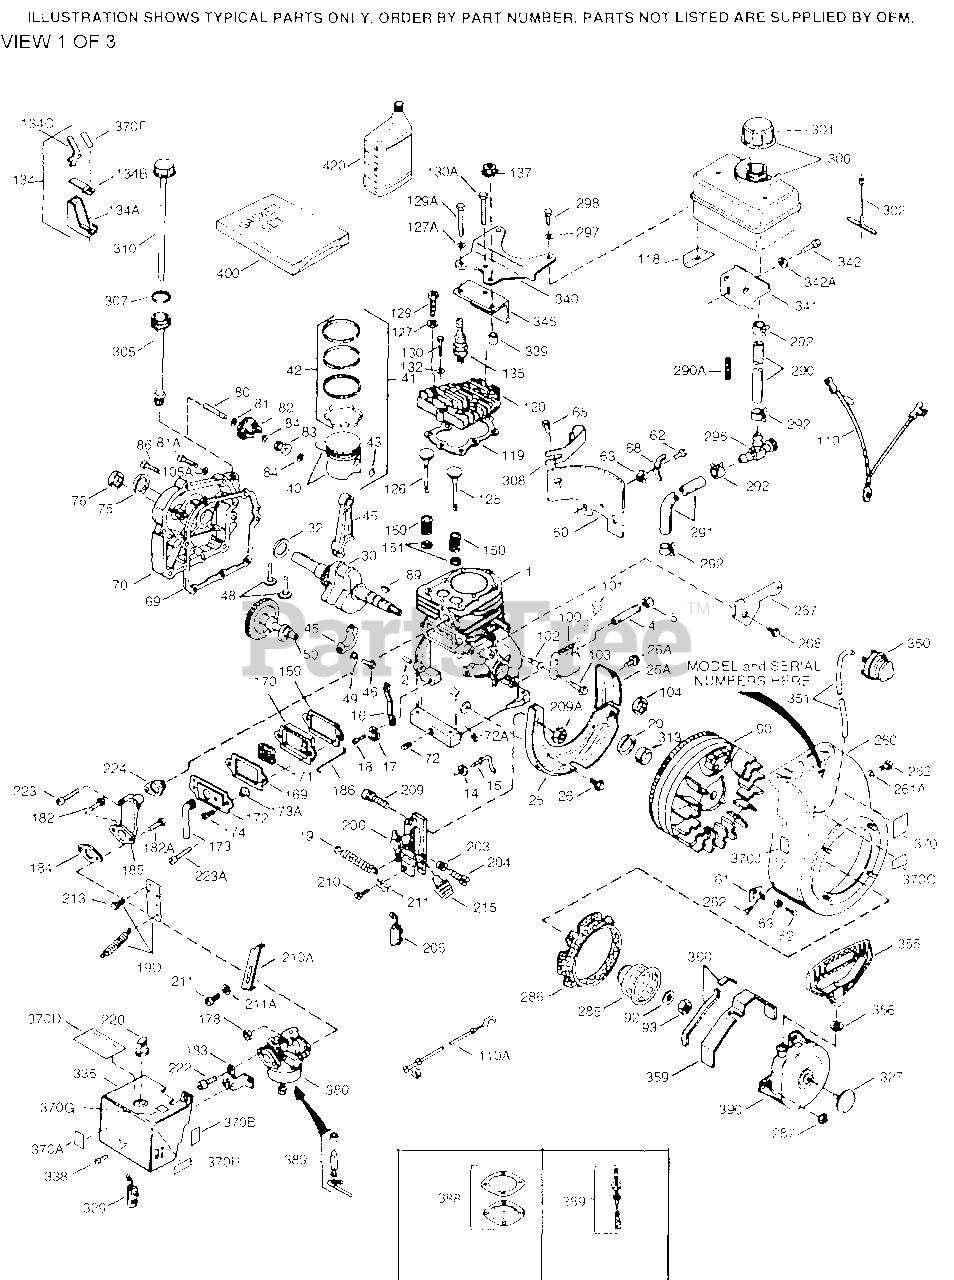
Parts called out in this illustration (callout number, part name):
1	"Cylinder (Incl. 2, 20 & 72)
2	Dowel Pin
14	Flat Washer
15	Governor Rod
16	Governor Lever
17	Governor Lever Clamp
18	Screw, 8-32 x 5/16"
19	Extension Spring
20	Oil Seal
25	Blower Housing Baffle
25A	Baffle Extension
26	Screw, 1/4-20 x 5/8"
26A	Screw, 8-32 x 1/2"
30	Crankshaft
40	Piston, Pin & Ring Set (Std.)
40	Piston, Pin & Ring Set (.010" OS)
40	Piston, Pin & Ring Set (.020" OS)
41	Piston & Pin Ass'y. (Std.) (Incl. 43)
41	Piston & Pin Ass'y. (.010" OS) Incl. 43
41	Piston & Pin Ass'y. (.020" OS) Incl. 43
42	Ring Set (Std.)
42	Ring Set (.010" OS)
42	Ring Set (.020" OS)
43	Piston Pin Retaining Ring
45	Connecting Rod Ass'y. (Incl. 46 & 49)
46	Connecting Rod Bolt
48	Valve Lifter
49	Oil Dipper
50	Camshaft (BCR)
60	Blower Housing Extension
65	Screw, 10-24 x 1/2"
69	* Cylinder Cover Gasket
70	Cylinder Cover Incl. 75, 80, 311 & 3 12
72	Oil Drain Plug (Sq. hd., 1/4-18)
75	Oil Seal
80	Governor Shaft
82	Governor Gear Ass'y. (Incl. 81)
83	Governor Spool
84	Retaining Ring
86	Screw, 1/4-20 x 1-1/4"
89	Flywheel Key (also available in Packa ged Part #740007B)
90	Flywheel
92	Belleville Washer
93	Flywheel Nut
100	Solid State Ignition
102	Solid State Mounting Stud
103	Screw, Torx T-15, 10-24 x 1"
110	Ground Wire
119	* Cylinder Head Gasket
120	Cylinder Head (Incl. 130)
125	Exhaust Valve (Std.) (Incl. 151)
125	Exhaust Valve (1/32" OS) (Incl. 151)
126	Intake Valve (Std.) (Incl. 151)
126	Exhaust Valve (1/32" OS) (Incl. 151)
130	Screw, 5/16-18 x 2"
131	Screw, 5/16-18 x 1-1/2"
135	Resistor Spark Plug - RJ17LM
150	Valve Spring
151	Valve Spring Cap
169	* Valve Cover Gasket
170	Breather Body
171	Breather Element
172	Valve Cover
173	Breather Tube
174	Screw, 10-24 x 1/2"
178	Nut & Lock Washer 1/4-28
182	Screw, 1/4-28 x 7/8"
184	* Carburetor To Intake Pipe Gasket
185	Intake Pipe
186	Governor Link
200	Control Bracket Incl. 203,204,206,209 ,209A
203	Compression Spring
204	Screw, 5-40 x 7/16"
206	Terminal
215	Control Knob
223	Screw, 1/4-20 x 1"
224	* Intake Pipe Gasket
260	Blower Housing
262	Screw, 1/4-28 x 7/16"
285	Starter Cup
287	Screw, 8-32 x 1/2"
290	Fuel Line (8.62")
292	Fuel Line Clamp
298	Screw, 1/4-15 x 7/8"
300	Fuel Tank (Incl. 292 & 301)
301	Fuel Cap (Red 1-1/2" ID) also availab le in Packaged Part #740005B
327	Starter Plug
340	Fuel Tank Bracket
342	Screw, 1/4-20 x 7/16"
345	Heat Baffle
370	Lubrication Decal
370A	Primer Decal
370B	Throttle Decal
370C	Choke Decal
380	Carburetor (Incl. 184)
390	Rewind Starter
400	* Gasket Set (Incl. items marked PK in notes) Incl. part #'s 26754A (1), 267 56 (1), 27234A (2), 27272A (1), 27677 A (1), 29673 (2), 29953C (1), 30081A (1), 31340A (1), 31619A (1), 31688A ( 2), 32649A (1), 33170A (1)
420	SAE 30 4-Cycle Engine Oil (Quart)
999	Summer Maintenance Kit (incl. Oil, Sp ark Plug, Air Cleaners (2), & Ultra-F resh)
